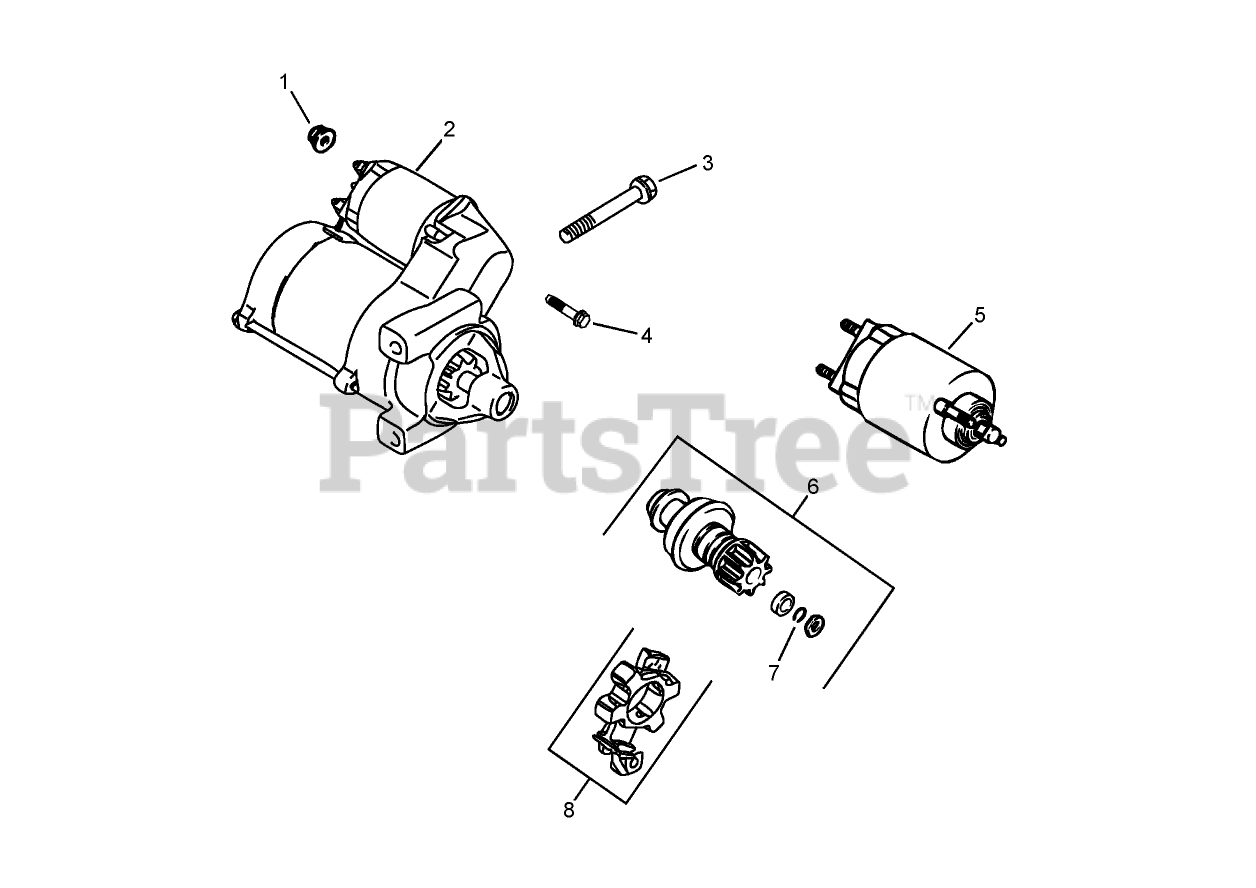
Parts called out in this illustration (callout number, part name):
1	NUT-FLANGE (M8X1.25)
2	Starter ASM (Includes4-8)
3	SCREW-FLG (M8X1.25X80)
4	SCREW-TORX HEAD, EXTERNAL
5	Solenoid Kit (Includes 4)
6	Pinion Drive Kit (Includes 7)
7	RING-RETAINING
8	BRUSH HOLDER KIT
